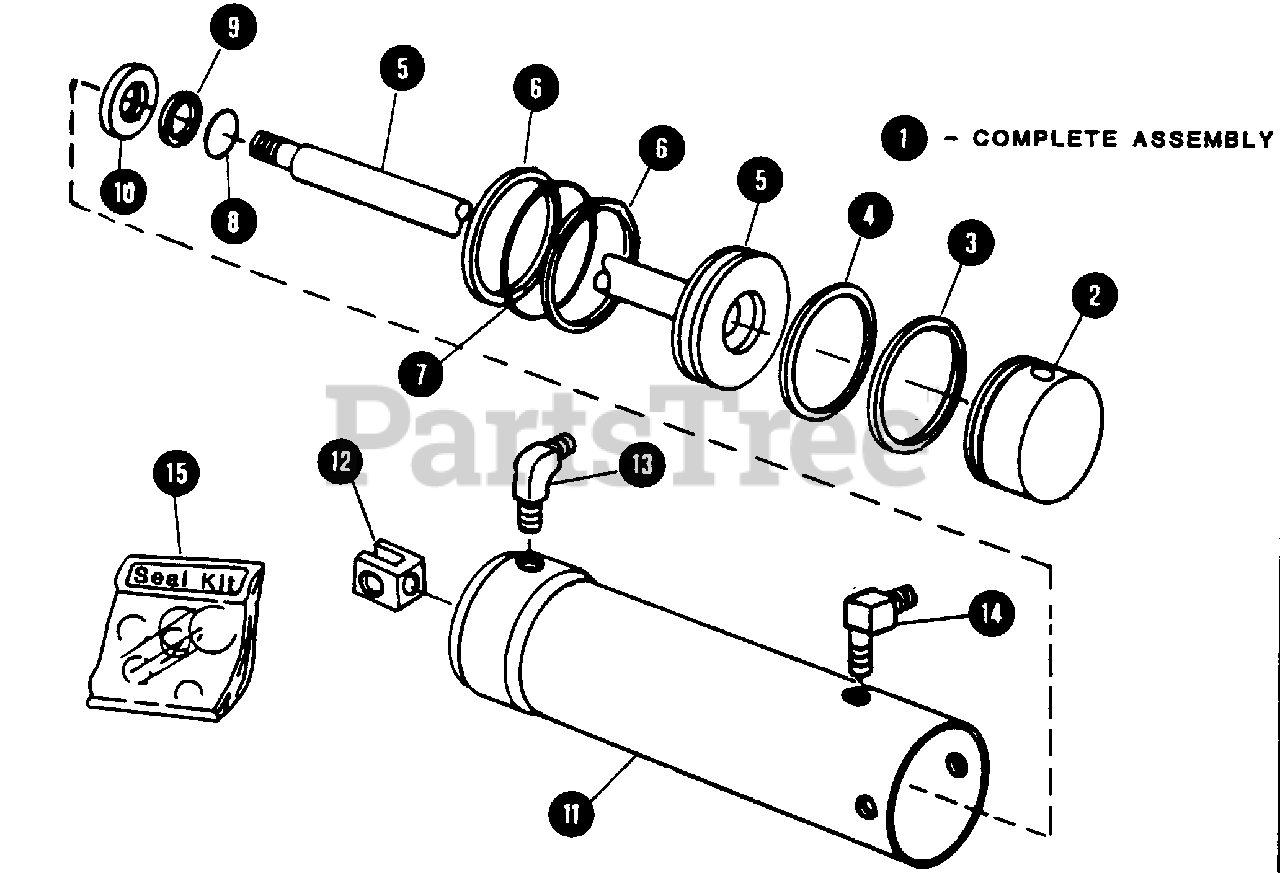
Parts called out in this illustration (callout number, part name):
1	CYLINDER, REAR LIFT ASSEMBLY
2	HEAD, CYLINDER
3	WASHER, HEAD O-RING BACKUP
4	O-RING, CYLINDER HEAD
5	PISTON-ROD ASSEMBLY
6	WASHER, PISTON O-RING BACK-UP
7	O-RING, PISTON
8	O-RING, PISTON ROD SEAL
9	WASHER, SEAL O-RING BACK-UP
10	WIPER, PISTON ROD
11	TUBE CYLINDER
12	FITTING, PISTON ROD END
13	ELBOW, 1/4-18 NPTF x 9/16-18 NF - 90°.
14	ELBOW, 1/4-18 NPTF x 9/16-18 NF - 90° (LONG)
15	KIT, SEAL REPLACEMENT
